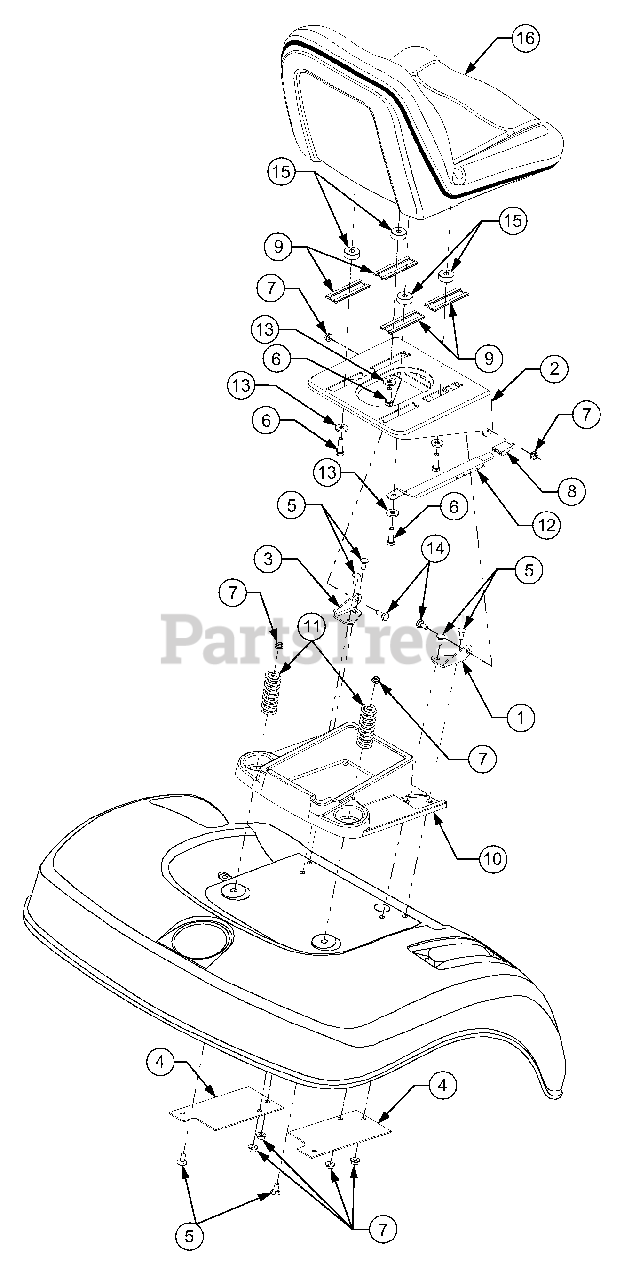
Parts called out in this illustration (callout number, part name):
6	Screw, Hx Cap Lock, 3/8-16 x 1.5 GR5
7	Nut, Hex Flange Lock, 5/16-18
8	Knob, Seat Adjuster
9	Slide, Seat
10	Tray, Tool
11	Spring, Comp, 1.9 OD x 2.4
12	Index Spring, Seat Adjuster
13	Washer, Flat, .406 x 1.0 x .105
14	Bolt, Shoulder
15	Spacer, Seat Slide Shoulder
16	Seat, High Back
